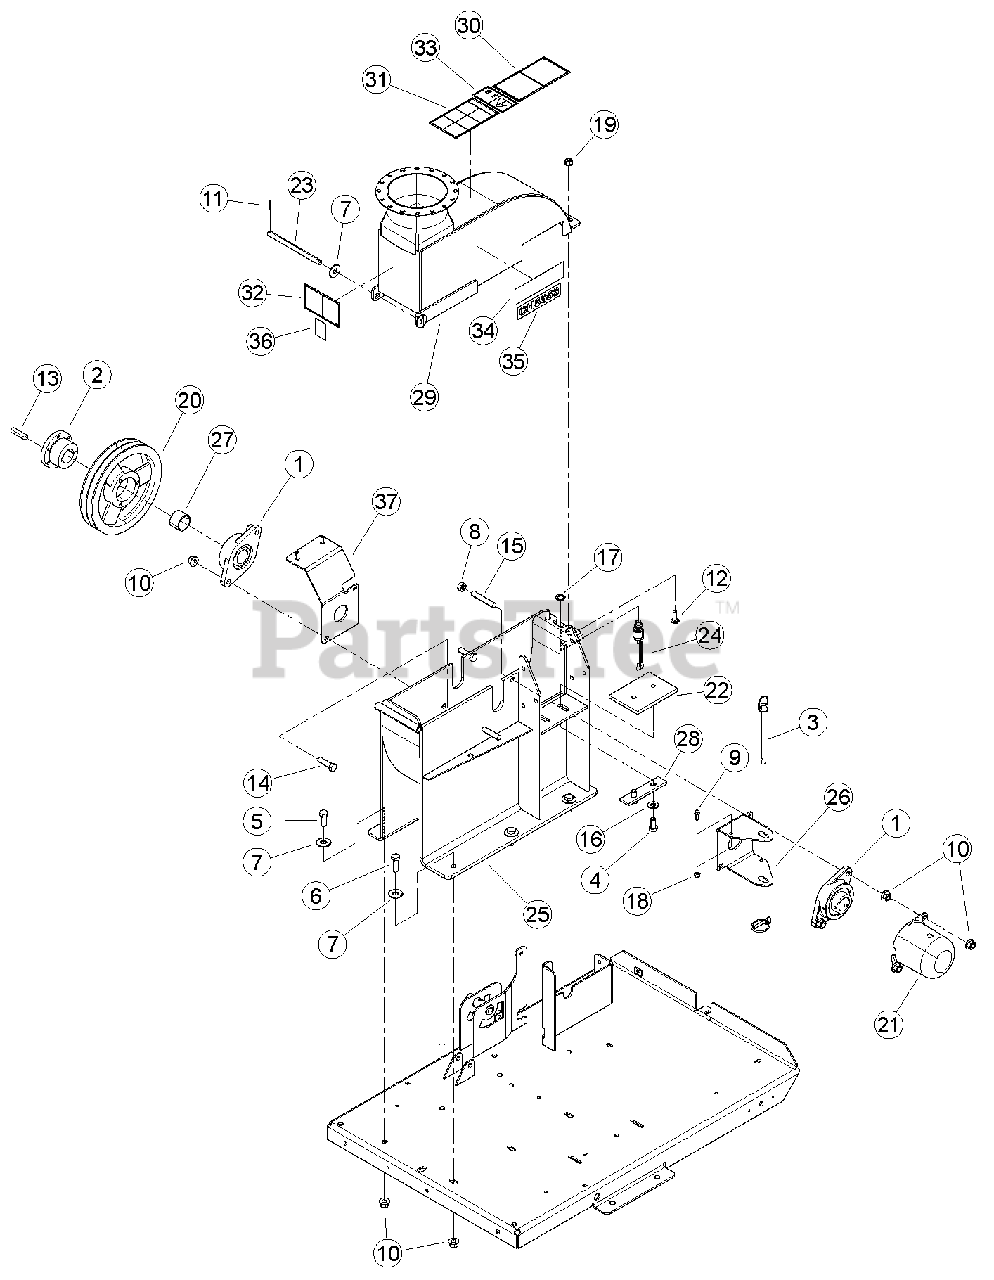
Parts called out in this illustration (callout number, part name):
1	BEARING, 1-1/2" 2-BOLT SET SCREW
2	BUSHING, SK 1-1/2"
3	PIN, HITCH 1/2 X 6-1/2 W/ LYNCH
4	BOLT, 1/2 X 1 GR5 HEX CAPSCREW ZP
5	BOLT, 1/2 X 1-1/4" GR5 HHCS NC ZP
6	BOLT, 1/2 X 1-1/2 HEX HD GR5 ZP
7	WASHER, 1/2" FLAT ZP
8	NUT, 1/2" CENTERLOCK GRB ZP
9	BOLT, 1/4-20 X 3/4 HWH GR5 CZP
10	NUT, 1/2-13 NYLOCK FLANGE
11	PIN, 1/8 X 1.00 ZP COTTER
12	BOLT, 3/8 X 1-1/4" GR5 CRG NC ZP
13	KEY, 3/8" SQ X 2" LG PLAIN
14	BOLT, 1/2 X 1 3/4 GR5 HCPS NC ZP
15	STUD, 1/2-13 X 3" LG B7 ZP
16	WASHER, 1/2 HI-STRENGTH SAE ZP
17	NUT, 5/8-32 JAM
18	NUT, 1/4-20 NYLOCK-FLANGE
19	NUT, 3/8-16 NYLOCK FLANGE
20	SHEAVE, 2B9.4 SK
21	CAP, LARGE SHAFT
22	ANVIL, 4 INCH CHIPPER
23	SHAFT, CHIPPER TOP PIVOT
24	ASSEMBLY, SEALED SWITCH
25	WELDMENT, CHIPPER BOTTOM
26	BRACKET, ROTOR LOCK
27	TUBE, 1.75 OD X .109 WALL X 1.150
28	STRIP, ADJUSTOR BLOCK
29	ASSEMBLY, CHIPPER TOP W/ DECALS
30	DECAL, KNIFE ACCESS ISO
31	DECAL, OPERATING INSTRUCTIONS ISO
32	DECAL, DISCHARGE ISO
33	DECAL, MAINTENANCE ISO
34	DECAL, ECHO BEARCAT 6.82 X 1.90
35	DECAL, MODEL CH5653
36	DECAL, ECHO BEARCAT QR CODE
37	WELDMENT, BELT GUARD SUPPORT (REPLACED AND SUPERSEDED PN 76941-00. FOR SERVICE ORDER PN 77249-12)
